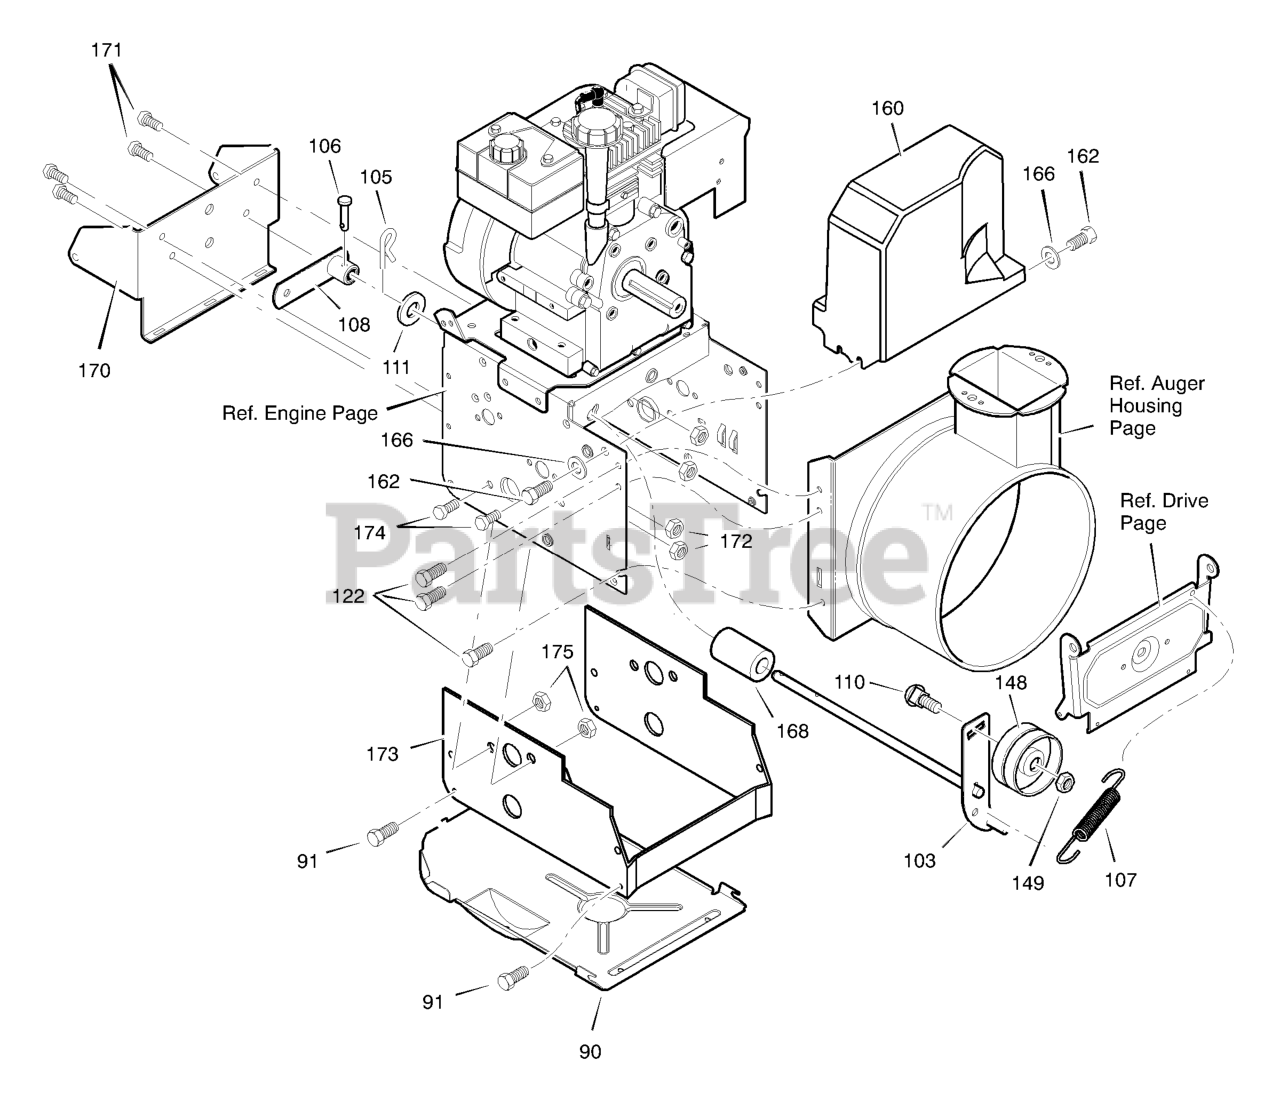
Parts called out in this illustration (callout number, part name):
90	COVER, BOTTOM
91	SCREW, 1/4-20X .62
103	IDLER ASSEMBLY, AUGER
105	PIN, HAIR .38DIAX1.64LG
106	PIN, CLEVIS 3/16" DIA
107	SPRING, TENSION
108	ASSY., SPRING ATTACH
110	BOLT, 3/8-16X1.25 CARR.
111	WASHER, FLAT
122	SCREW, TAP 5/16-18 X .50
148	PULLEY, IDLER
149	NUT, JAM 3/8-16
160	COVER, BELT
162	SCREW, TAP 1/4-20 X .63
166	WASHER, FLAT
168	SPACER, AUGER BRACKET
170	BRACKET, TRACK SUPPORT
171	SCREW, 5/16-18 x 0.75
172	NUT, 5/16-18
173	EXTENSION, FRAME
174	SCREW, 3/8-16 X 0.75
175	NUT, 3/8-16
